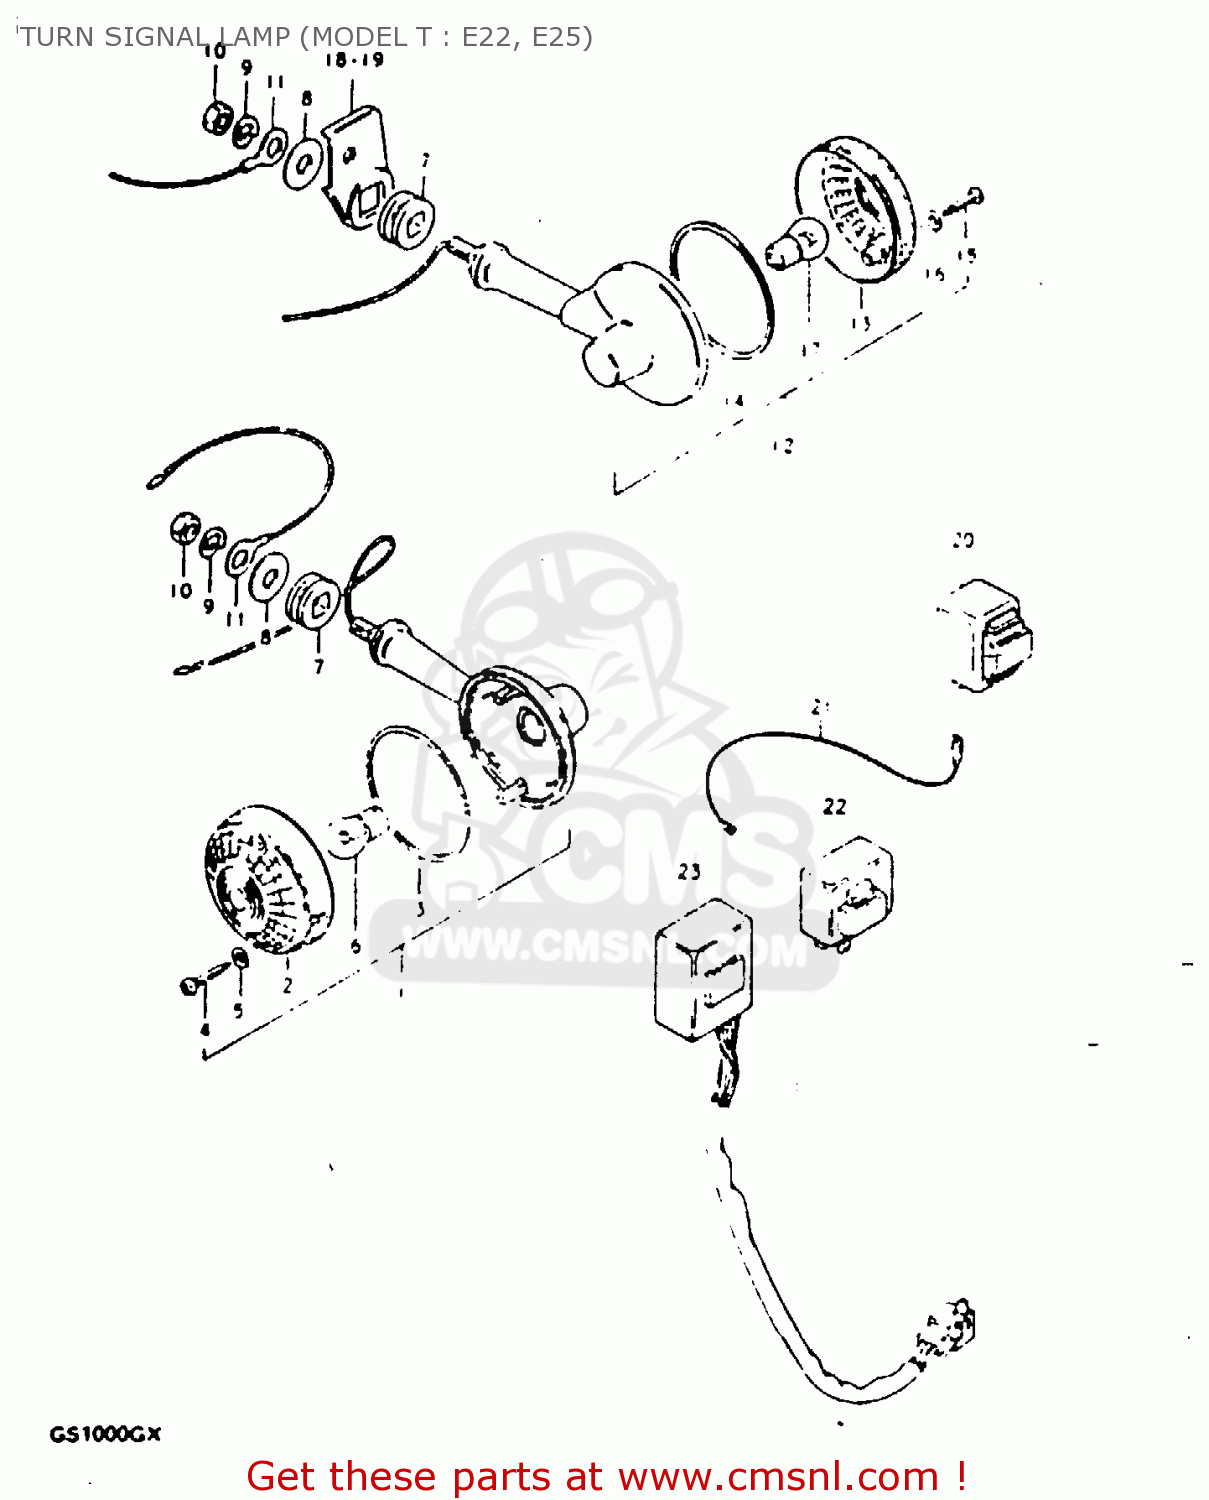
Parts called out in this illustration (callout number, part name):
1	LAMP, REAR TURN SIGNAL
2	LENS
3	GASKET (NAS)
4	SCREW (4X30)
5	GASKET (NAS)
6	BULB(12V21W)
7	CUSHION
8	WASHER (10.5X30X2.3)
9	LOCK WASHER
10	NUT
11	LEAD WIRE,EARTH
12	LAMP, REAR TURN SIGNAL
13	LENS
14	GASKET (NAS)
15	SCREW (4X30)
16	GASKET (NAS)
17	BULB(12V21W)
18	BRACKET,RR TURNSIGNAL LAMP,R
19	BRACKET,RR TURNSIGNAL LAMP,L
20	RELAY, TURN SIGNAL
21	LEAD WIRE, RELAY EARTH
22	RELAY ASSY,TURNSIGNAL
23	UNIT,TURN SIGNAL CONTROL
